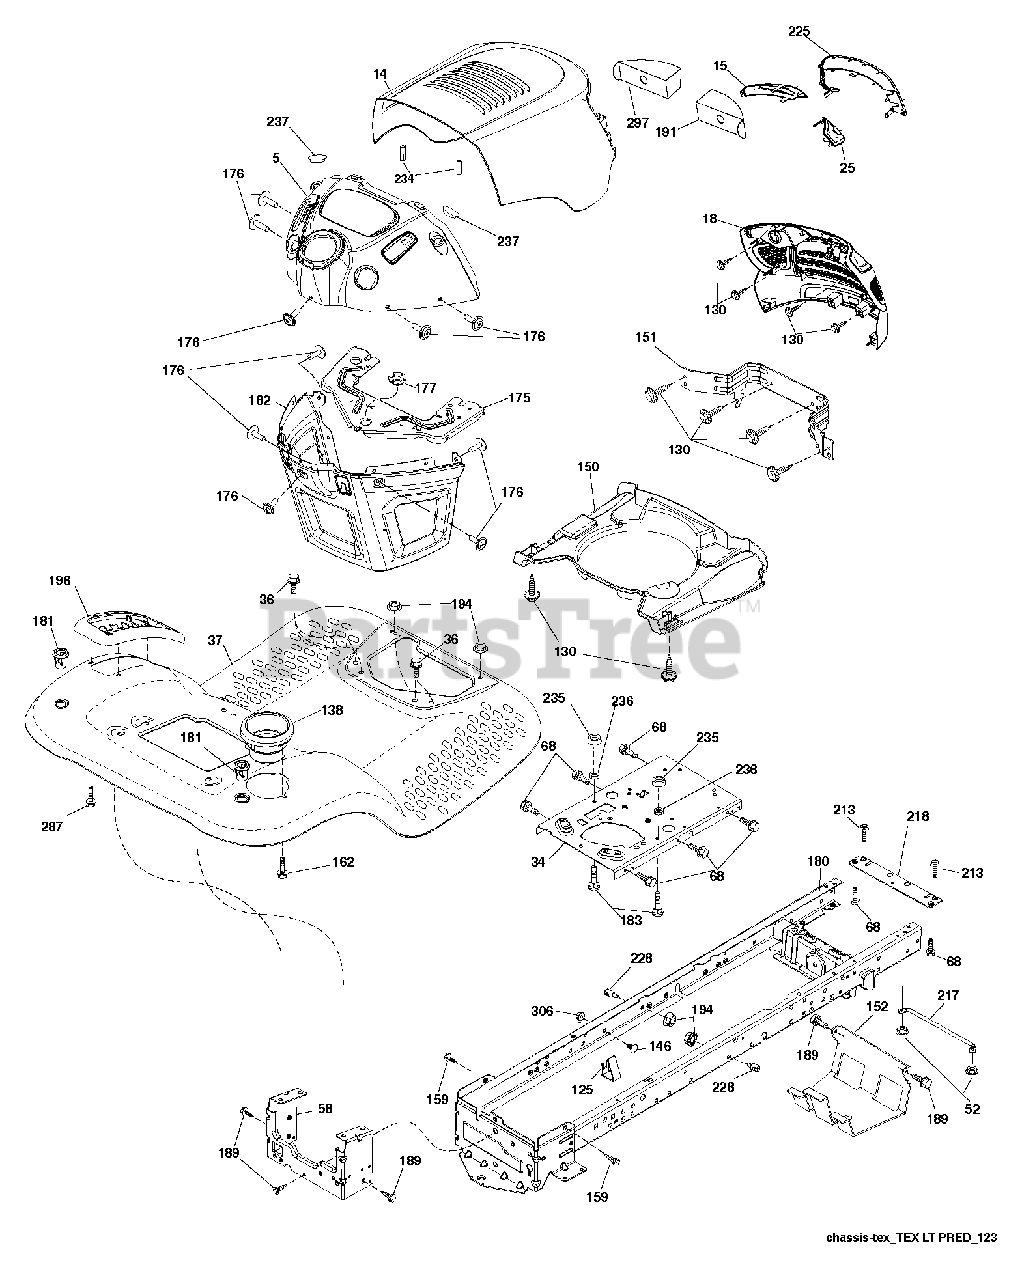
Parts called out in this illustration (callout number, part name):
5	DASH.PRED.LT.CC.ICY.N/SRV.BLK
14	HOOD.PREDATR.LT.U-FRM.TPVNT428
15	MCCULLOCH.LT.LENS.LEFT
18	GRILL.LT.GRNREIC.PPRO
25	MCCULLOCH.LT.LENS.RIGHT
34	PLATE.ENGINE.WELDED.CHASSIS
36	SCREW 5/16"
37	FENDER.TLT.W/CPH.428
52	LOCKNUT
58	DRAWBAR UPPER 2PC SMALL FENDER
68	SCREW LT
125	CLIP.FUEL.LINE
130	SCREW.#10 X 0.750.BOS (2 2)
138	CUPHOLDER.TL.TEX.BLACK
146	BOLT.RDHD.SHT.SQNK.3/8-16X5/8
150	DUCT.AIR.TOP.VENT.PREDATOR.LT
151	BRACKET.PIVOT.ALPHA.LT
152	SHIELD.BROWNING.W/TEX
159	SCREW, 3/8-16X3/4
162	SCREW.HI-LO.CONSOLE
175	CROSSMEMBER
176	SCREW.#10-24X5/8.RN.QU
177	BUSHING STEERING
180	CHASS.WLDMNT.TL.12GA/2P.48/54
181	FEND/FTRST.PCH.CPH.NFW
182	DASH.LOWER.PREDATOR LT
183	BOLT.5/16-18X1-1/4 FULL THD
189	SCREW
191	INSERT.REFLECT.RH.MCC.LT.RT
194	NUT LOCK HEX FLANGE 5/16-18
213	BOLT
217	ROD.PIVOT.HOOD
218	X-PIECE.HOOD.STOP.NON/
225	MCCULLOCH.LT.TRIM.RING
228	STUD.FASTNER.W/ANTI-ROTATE
234	BUMPER.HOOD.TEX.HUSQVARNA
235	SPACER FENDER
236	NUT.CENTERLOCK.5/16-
237	PLUG.MOUNT.CARGO.BLK
287	SCREW 1/4X20
297	INSERT.REFLECT.MCC.LT.LF/RT
306	NUT LOCK FLG 3/8-16 UNC
